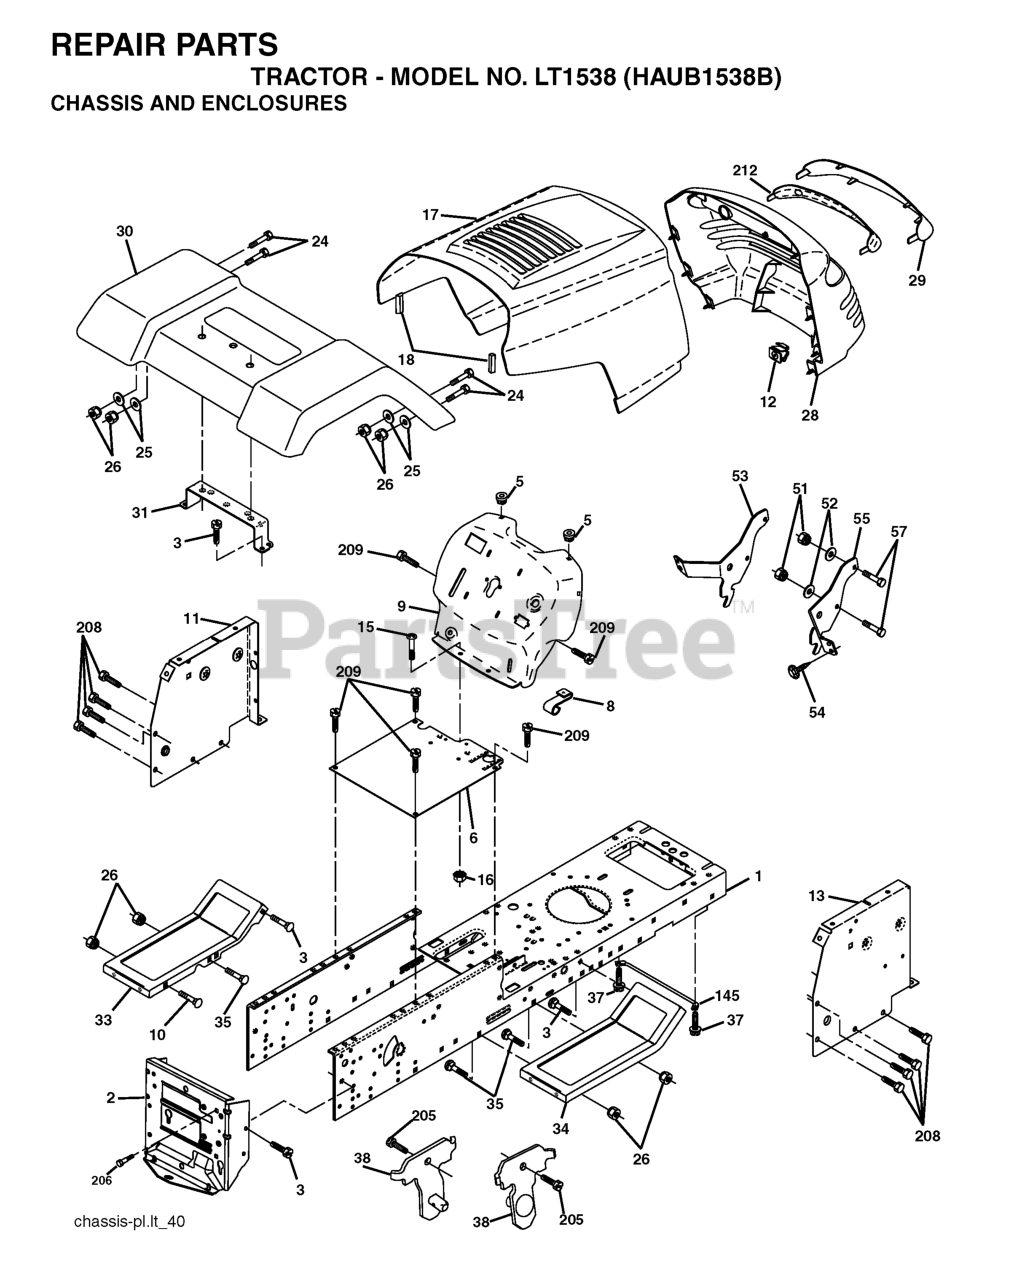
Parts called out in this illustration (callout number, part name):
2	DRAWBAR, 12GA
3	SCREW 3/8-16X3/4
5	BUMPER.RUBBER.HOOD
6	PLATE
8	CLIP RETAINER
10	BOLT D
11	PANEL.DASH.LH.LTX
13	PANEL DASH RH
15	Screw, Machine, Truss Head 5/16-18 UNC x 3/4
16	NUT
17	HOOD ASM.
18	BUMPER.HOOD.LARGE.1.75"
25	WASHER
26	NUT
28	GRILL ASSEMBLY
29	LENS P/L
30	FENDER
31	BRACKET FENDER
33	FOOTREST PNT LH
34	FOOTREST PNT RH
37	Screw 5/16-18 x 1/2 Hex, Self Tapping 5/16-18 x 1/2
38	BRACKET.ASM.PIVOT.MOWER.REAR
51	LOCKNUT.NYLOC.1/4-20
53	BRACKET.GRILLE.LH
54	SCREW.HEX.WS.HD.8-18 X 7/8
57	BOLT
145	ROD PIVOT CHASSIS/HOOD
206	SHOULDER BOLT 5/16-18TT
208	SCREW 3/8-16X1/2
209	SCREW, 3/8-16X3/4
212	REPL BY 532 1745-03
